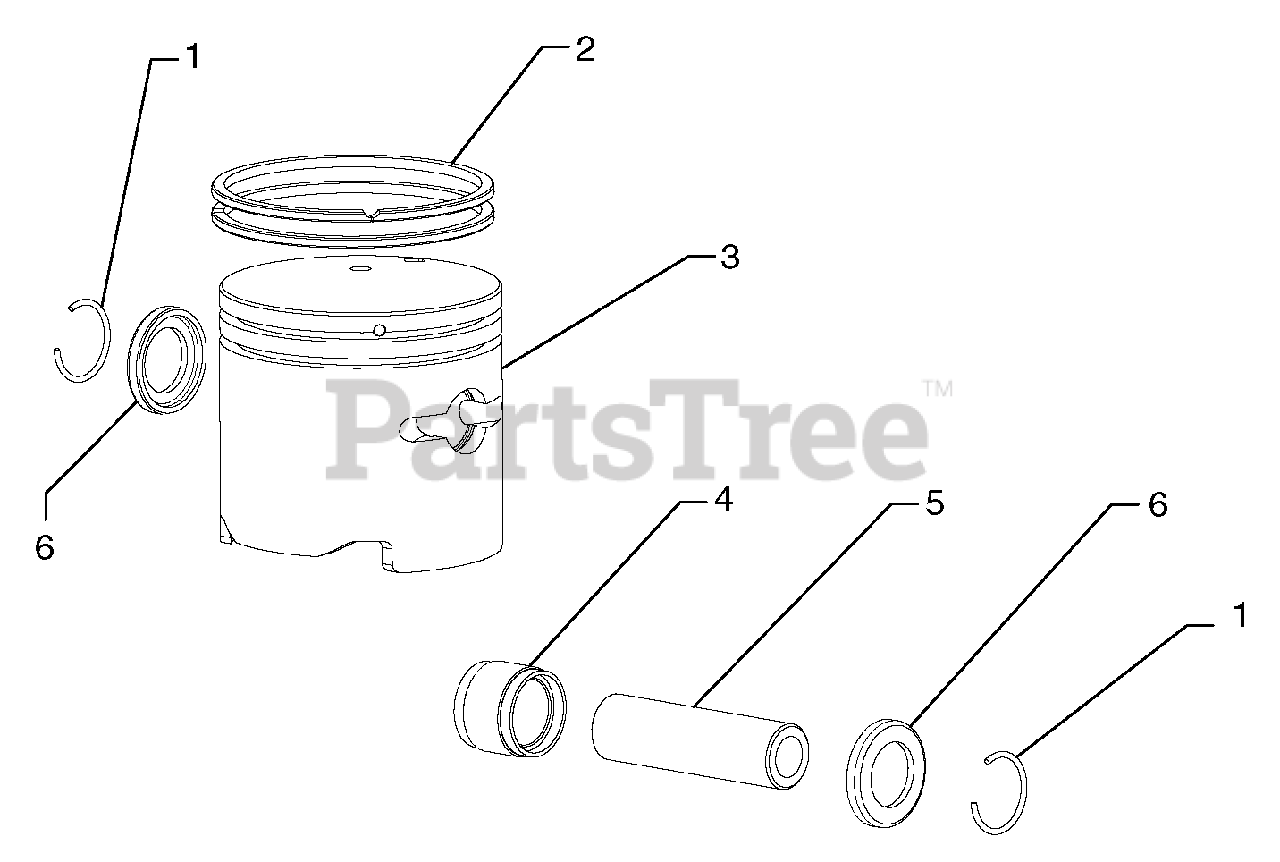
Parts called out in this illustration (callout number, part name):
1	Wrist Pin Clip Ring
2	Piston Ring
4	Needle Bearing (ID 8 x 8.8)
5	Wrist Pin
